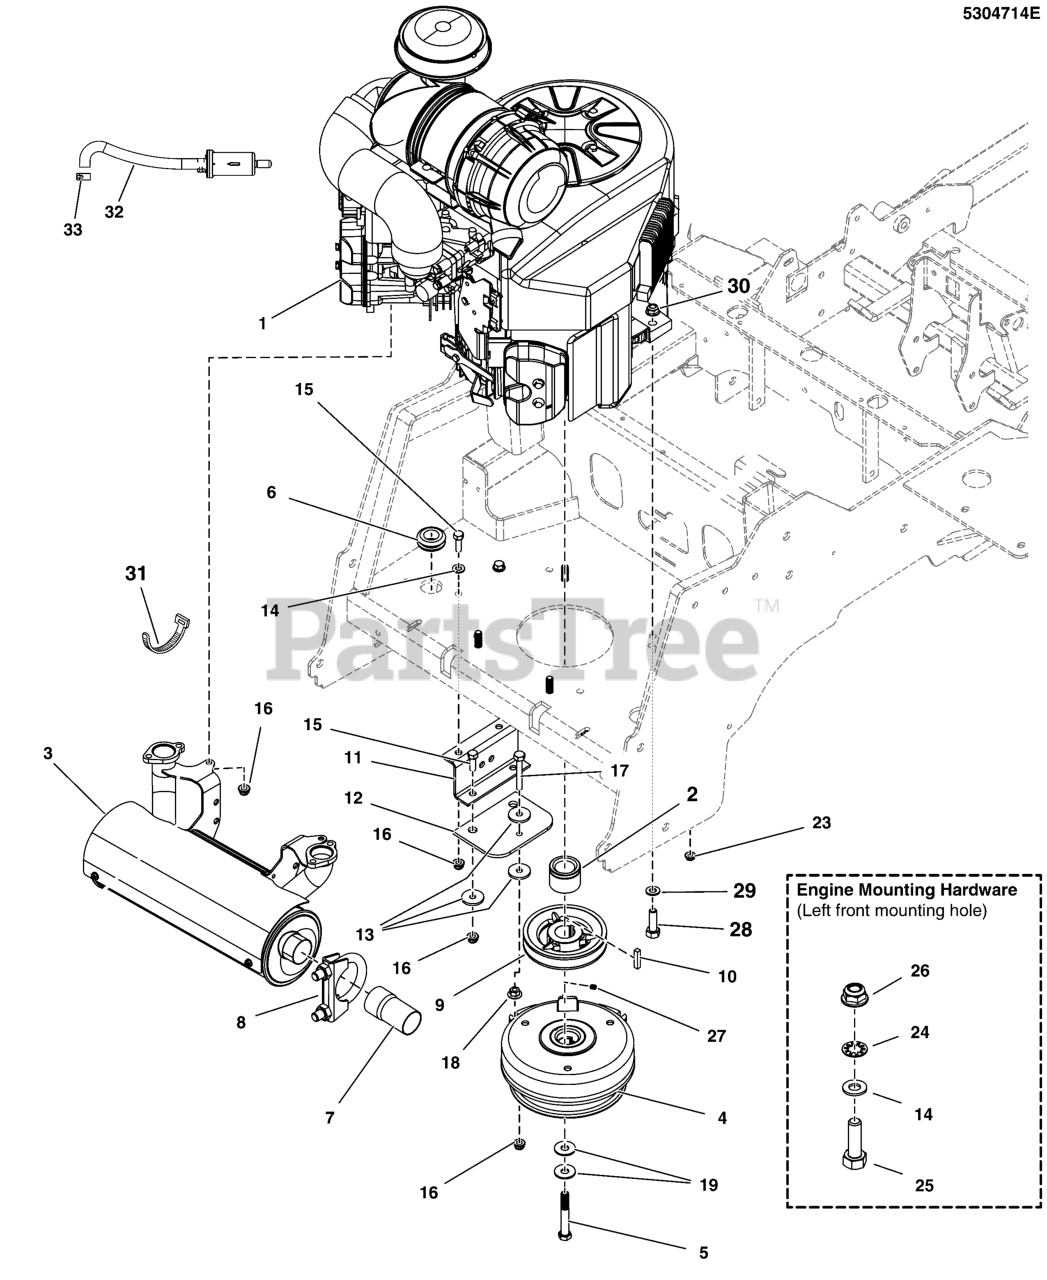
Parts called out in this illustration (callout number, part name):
1	ENGINE, Briggs & Stratton
2	SPACER, 1.13 X 1.75 X 1.35, CZ
4	CLUTCH
5	BOLT, CRANKSHAFT, 7/16-20 X 3-1/4, GD8
6	GROMMET, 7/8"ID, 1/4" THICK STK
7	PIPE, Exhaust
8	CLAMP, Muffler
9	PULLEY, 4.75 OD X 1-1/8 BORE, BC-48
10	KEY, 1/4 SQ. X 1-1/4
11	ANCHOR, CLUTCH, IS600-IS700 - BLK
12	PAD, Clutch Anchor
13	WASHER, CLUTCH ANCHOR, 5/16
14	WASHER, 5/16, Flat SAE, Zinc/Clear
15	CAPSCREW, Hex Head, 5/16-18 x 1
16	NUT, Flange Nylock, 5/16-18
17	BOLT, 5/16-18 X 2-1/4
18	NUT, 5/16-18 HEX SERRATED FLANGE (LARGE)
19	BELLEVILLE, WASHER, 1.1875 X .442 X .089
20	TIE, 6" Self-Locking
20	TIE,SELF-LOCKING, 24"
21	Hose/Filter Assembly
22	CLAMP, Hose
23	GUARD
24	WASHER, 5/16" Internal Tooth Lock
25	BOLT, 5/16-24 X 1-3/4, GD8, PHOS
26	NUT, 5/16-24, TOP LOCK FLANGE, GD8 PHOS
27	SCREW, Set, 5/16-18 X 3/8
28	CAPSCREW, Hex Head, 3/8-16 X 1-3/4
29	WASHER, .406
30	NUT, Hex Flange, Nylock, 3/8-16
